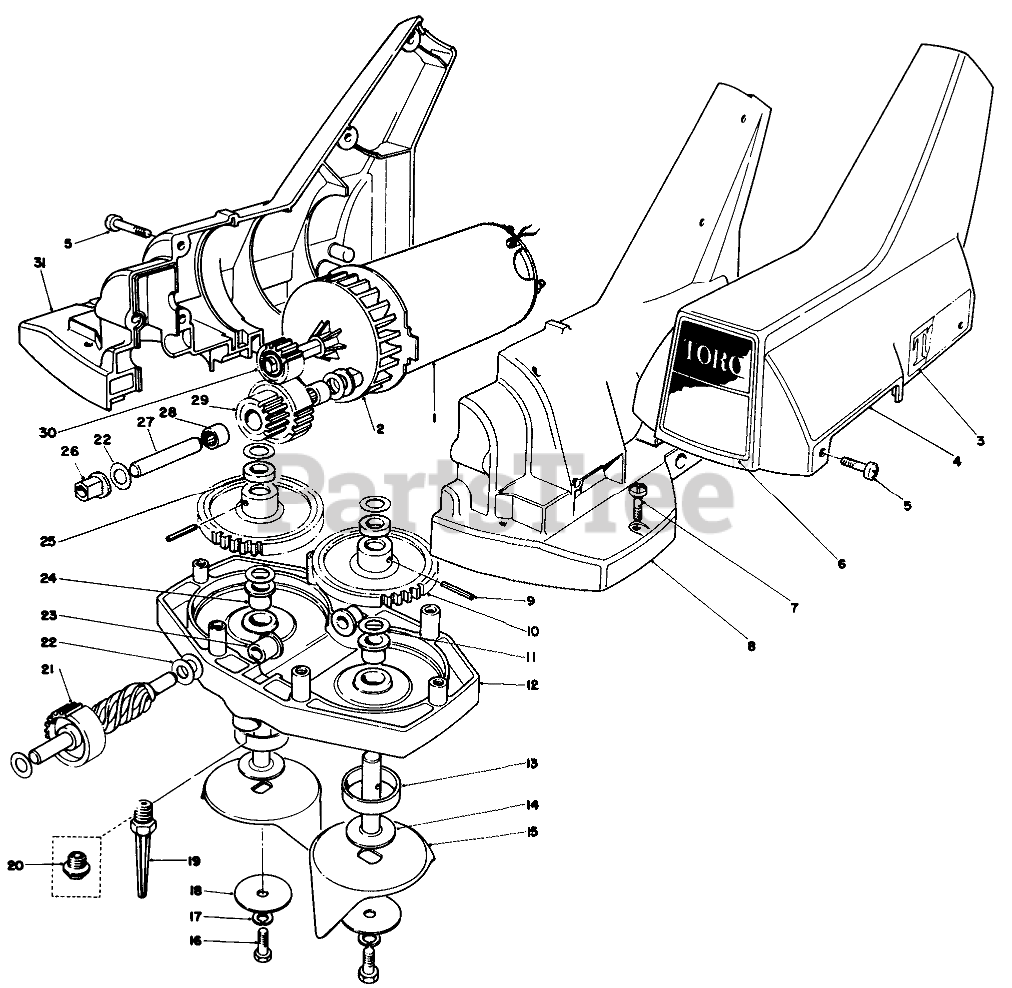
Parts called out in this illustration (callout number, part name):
1	Motor (Incl. Ref. #2 & 30)
3	Decal-Toro
4	Cover
6	Decal
7	#10-32 PHILLIPS TF SC
8	Upper Case L.H.(Incl. Ref. #24)
9	PIN-GROOVED
10	HELICAL GEAR
11	THRUST RACE
12	Lower Case (Incl. Ref. #24)
13	SPACER
14	Tine Shaft
15	Tine Cup
16	1/4-20 X 5/8 CAPSCREW
17	WASHER-LOCK
18	WASHER-FLAT
19	STABILIZER SPIKE
21	Worm Shaft w/Gear
22	THRUST WASHER
23	Bushing
24	BUSHING-FLANGE
25	COLLAR
26	Sleeve
27	Idler Shaft
28	Bearing
29	CLUSTER GEAR
30	Driver Gear
31	Upper Case R.H. (Incl. Ref. #24)
